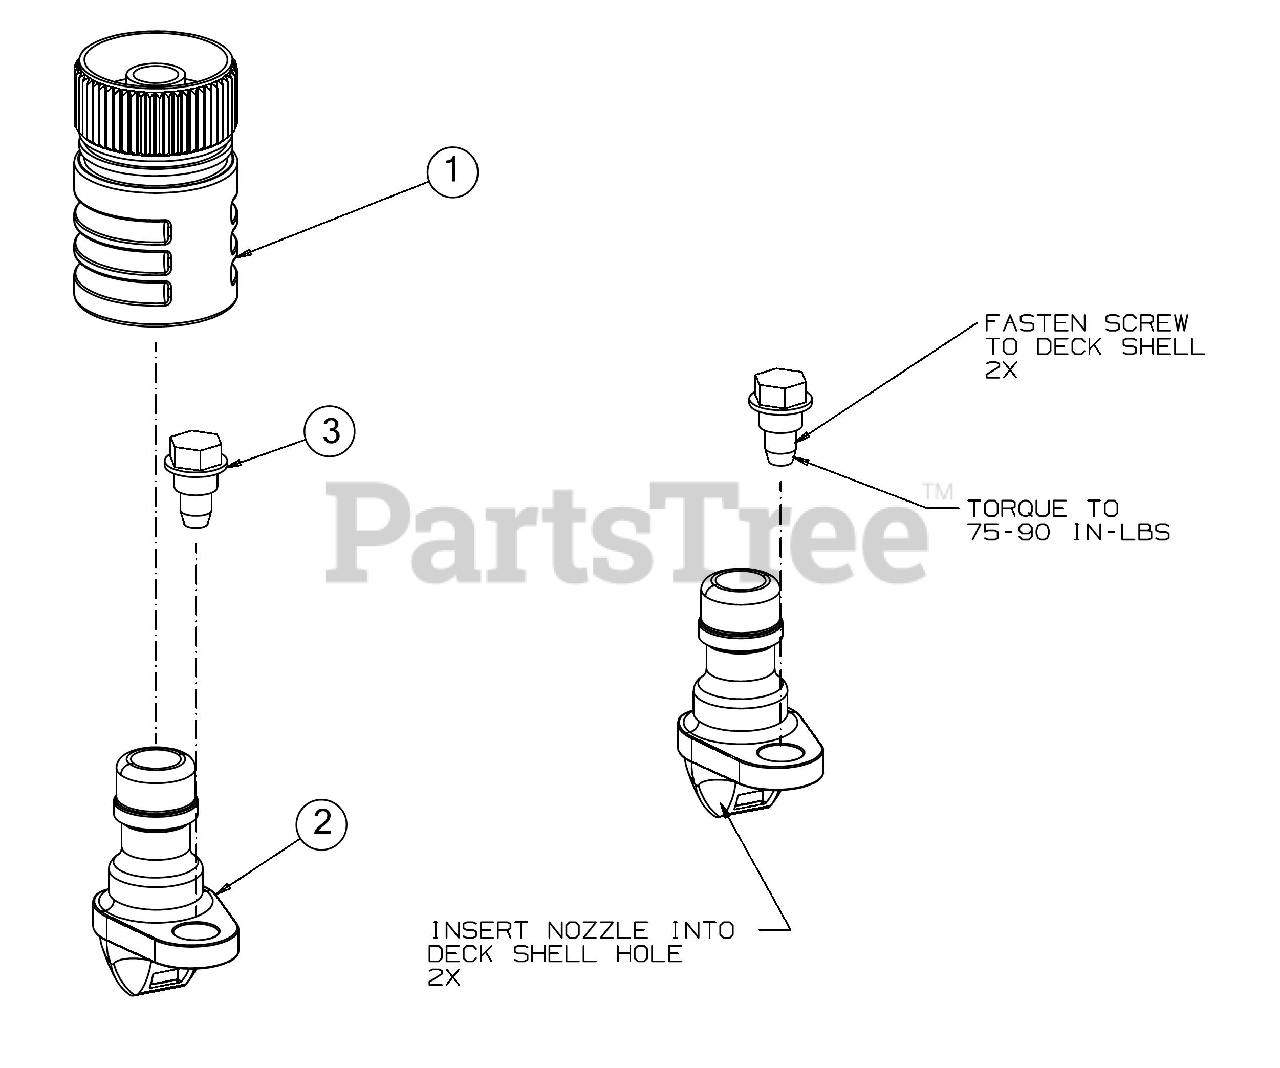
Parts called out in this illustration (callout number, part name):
1	WATER NOZZLE
2	DECK WASH NOZZLE
3	SHOULDER SCREW 1/4-20 X .50
